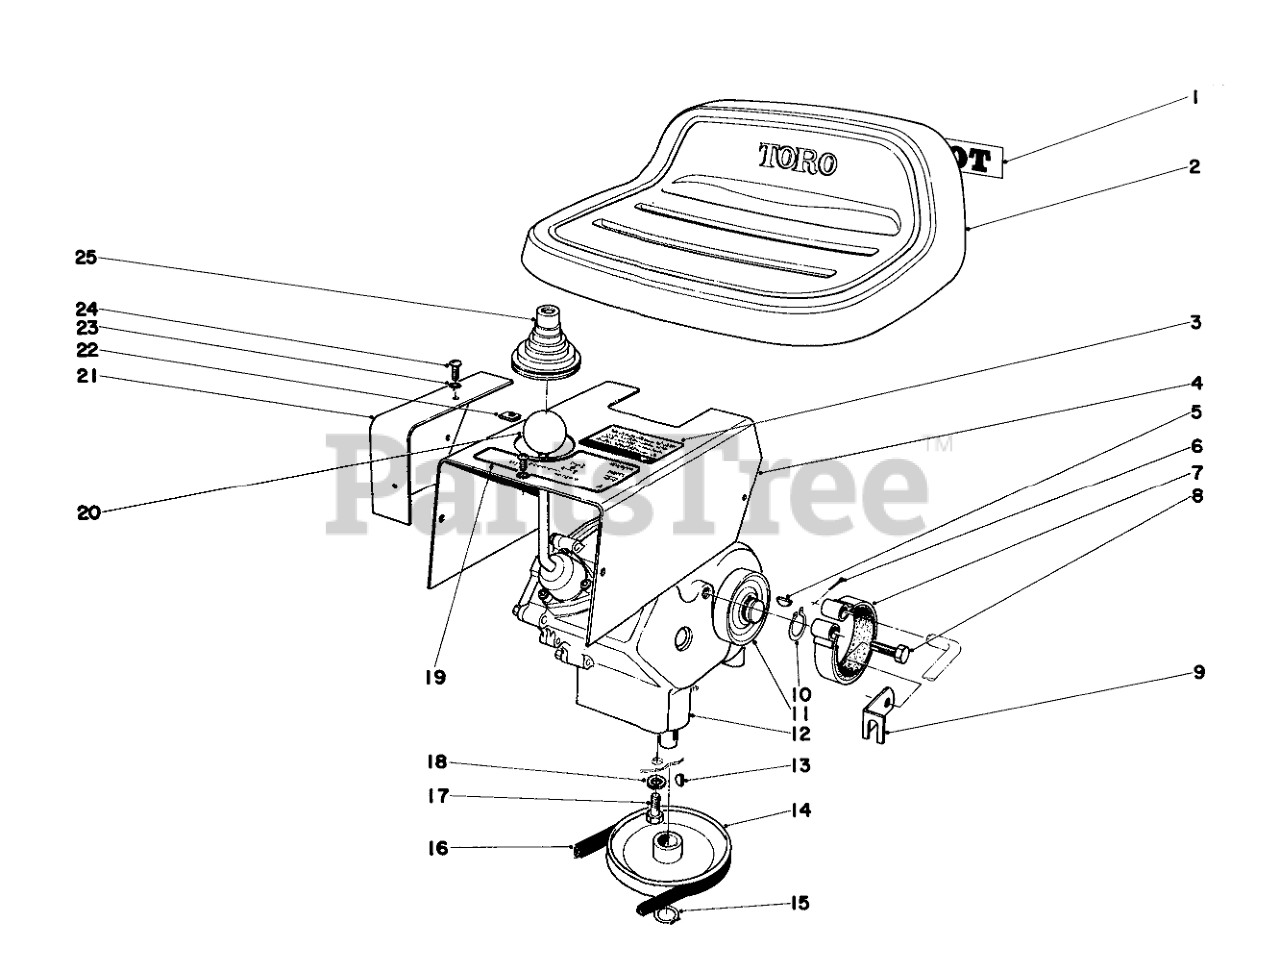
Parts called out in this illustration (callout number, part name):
1	Decal
3	Decal-Caution
4	Cover Transmission
5	KEY-WOODRUFF
6	PIN-COTTER
7	Brake Band
8	SCREW-HH
9	Retainer Brake Rod
10	Ring-Snap
11	Brake Drum
12	Transmission
13	KEY-WOODRUFF
14	Pulley
15	RING-SNAP, EXTERNAL
16	TRANS TO ENGINE BELT
17	SCREW-HH
18	WASHER-LOCK/SP
19	Decal, Shift Pattern (Mod. 57003)
21	Chain Guard
22	NUT-CLIP,U
23	WASHER-LOCK, EXT
24	10-24 X 3/8 PAN HD SC
25	Boot Shift Lever
